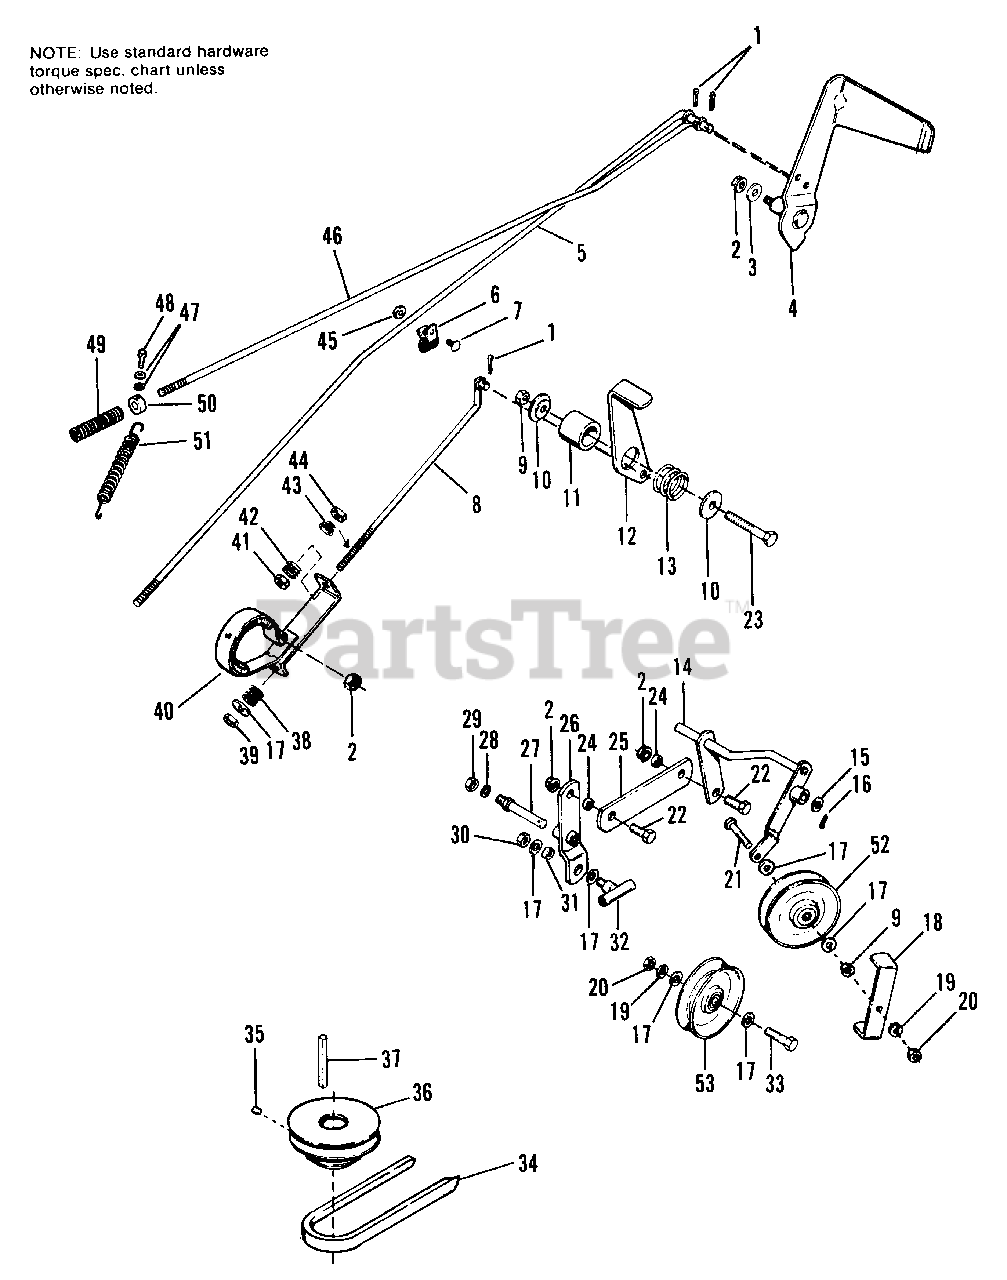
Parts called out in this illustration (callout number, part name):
1	PIN, Cotter, 3/32 x 3/4
2	LOCKNUT, Flange, 3/8-16
3	WASHER, Plain, 3/8
4	PEDAL ASSY., Foot
5	ROD, Brake
7	BOLT, Rd. Hd., 5/16-18 x 1/2
8	ROD, Parking Brake
9	LOCKNUT, Hex, 3/8-16
10	WASHER, Special
14	ARM ASSY., Idler
16	PIN, Cotter, 1/8 x 1
17	WASHER, Plain, 5/16
18	GUIDE, Belt
19	LOCKWASHER, 3/8
20	NUT, Hex, Full, 3/8-16
21	CAPSCREW, Hex
22	CAPSCREW, Hex Hd., 3/8-16 x 7/8
23	CAPSCREW, Hex Hd., 3/8-16 x 2-3/4
25	ARM, Pivot
26	PIVOT ASSY., Arm
28	LOCKWASHER, 7/16
29	NUT, Hex, Full, 7/16-14
30	LOCKNUT, Jam, 5/16-18
32	GUIDE ASSY., Rod
33	CAPSCREW, Hex Hd., 3/8-16 x 1-1/4
34	BELT, V
35	SETSCREW, 5/16-18 x 5/16
36	PULLEY, Engine
39	LOCKNUT, Hex, 5/16-18
40	BAND ASSY., Brake
41	NUT, Hex, Full, 5/16-18
44	LOCKNUT, Elastic, 5/16-18
45	LOCKNUT, Flange, 5/16-18
46	ROD, Clutch
47	WASHER, Flat, 1/4
48	SETSCREW, 1/4-20 x 3/4
50	COLLAR, Set
51	SPRING
52	PULLEY, Idler
53	PULLEY, Idler
